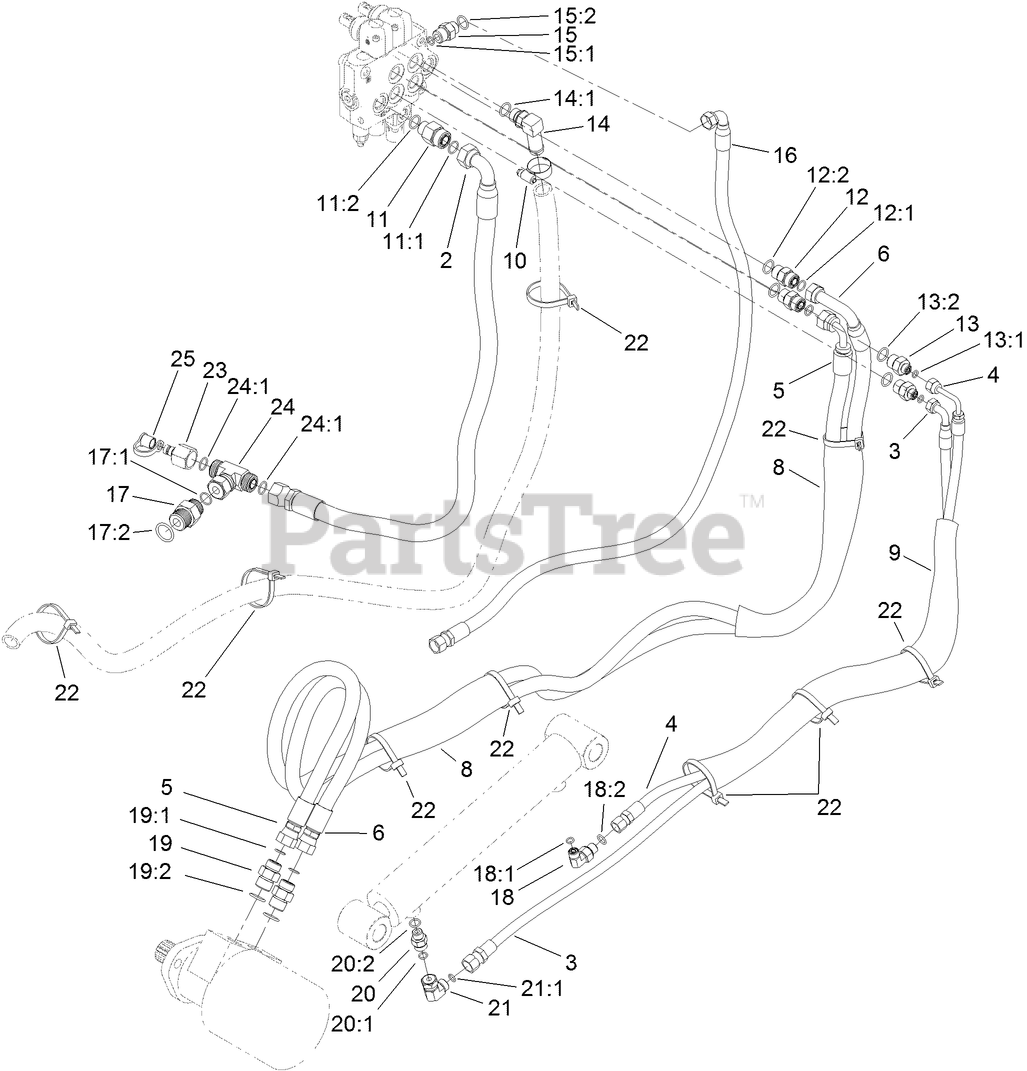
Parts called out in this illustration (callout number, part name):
2	HOSE-HYD
3	HOSE-HYD
4	HOSE-HYD
5	HOSE-HYD
6	HOSE-HYD
8	SLEEVE-PROTECTIVE
9	SLEEVE-PROTECTIVE
10	CLAMP-HOSE
11	FITTING-STR
11:1	O-RING
11:2	O-RING
12	FITTING-STRAIGHT
12:1	O-RING
12:2	O-RING
13	FITTING-STR
13:1	O-RING
13:2	O-RING
14	FITTING-ELB 90
14:1	O-RING
15	FITTING-STRAIGHT
15:1	O-RING
15:2	O-RING
16	HOSE-HYD
17	FITTING-STRAIGHT
17:1	O-RING
17:2	O-RING
18	FITTING-ELBOW 90
18:1	O-RING
18:2	O-RING
19	FITTING-STRAIGHT
19:1	O-RING
19:2	O-RING
20	VALVE-CHECK
20:1	O-RING
20:2	O-RING
21	FITTING-HYD, 90 DEG
21:1	O-RING
22	TIE-CABLE
23	NIPPLE
24	FITTING-HYD, TEE
24:1	O-RING
25	CAP-DUST
